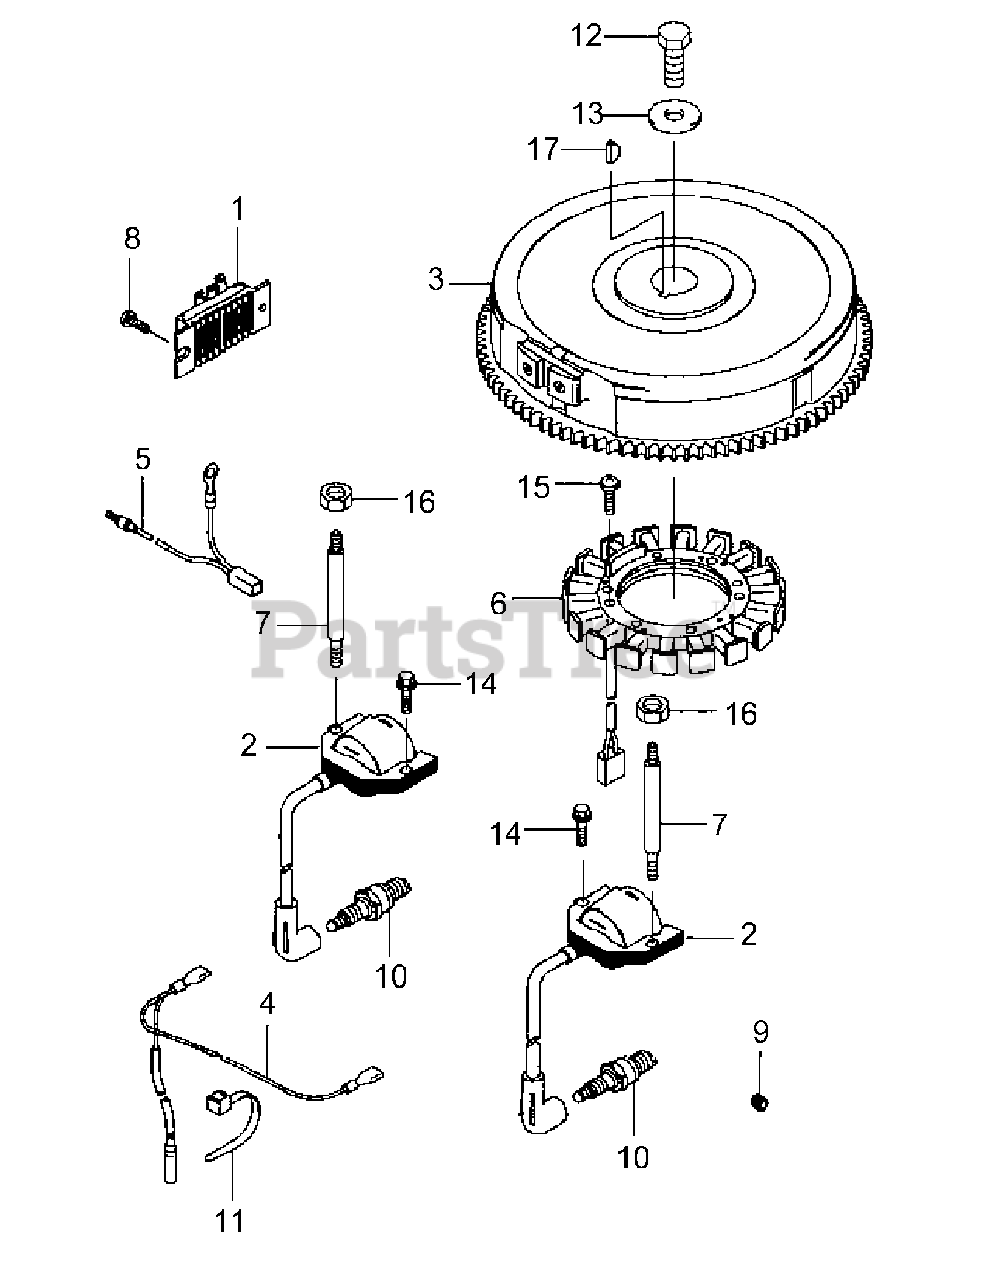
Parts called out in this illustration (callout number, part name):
1	VOLTAGE REGULATOR
2	IGNITION COIL ASSY.
3	FLYWHEEL
6	CHARGING COIL
7	STUD
10	SPARK PLUG
14	FLANGED BOLT
15	PAN SCREW
17	WOODRUFF KEY
